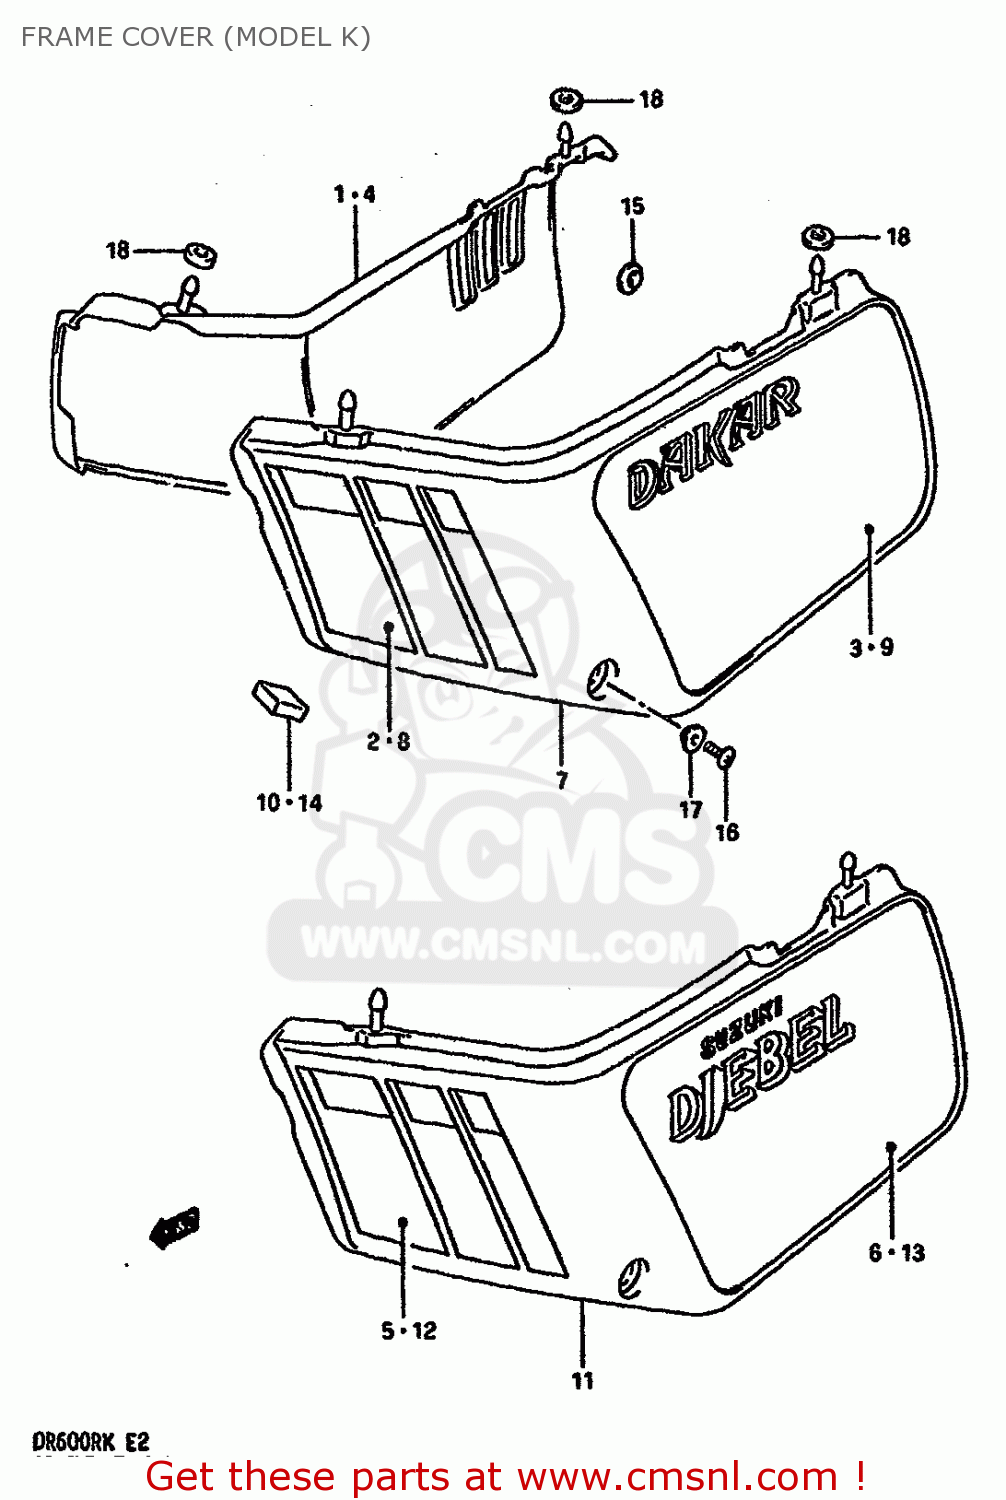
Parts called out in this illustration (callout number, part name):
1	COVER,FRAME RH (WHITE)
2	TAPE,FRONT RH
3	TAPE,REAR RH
4	COVER,FRAME RH (WHITE)
5	TAPE,FRONT RH
6	TAPE,REAR RH
7	COVER,FRAME LH (WHITE)
8	TAPE,FRONT LH
9	TAPE,REAR LH
10	CUSHION,FRAME COVER
11	COVER,SIDE,L(WHITE)
12	TAPE,FRONT LH
13	TAPE,REAR LH
14	CUSHION,FRAME COVER
15	CUSHION
16	SCREW 6X12
17	WASHER
18	CUSHION,SIDE COVER BOSS
